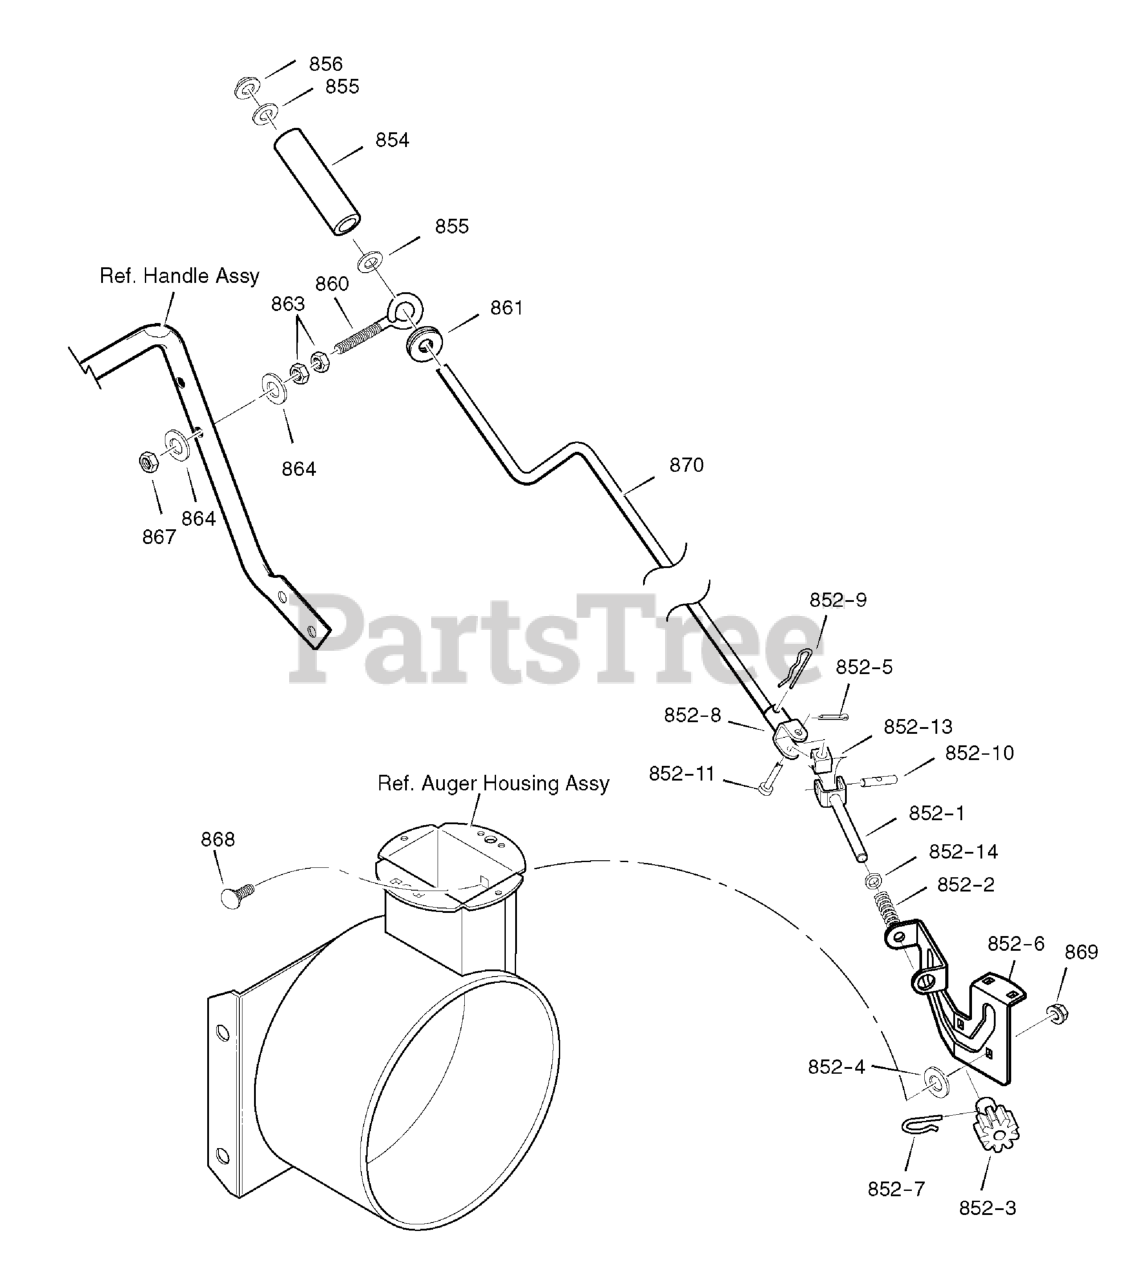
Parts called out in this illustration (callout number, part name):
852-1	YOKE & ROD ASSEMBLY
852-2	SPRING, Compression
852-3	GEAR, Chute Rotation
852-4	WASHER
852-5	PIN, Cotter
852-6	BRACKET, Gear Mount
852-7	PIN, Hair
852-8	YOKE ADAPTER ASSEMBLY
852-9	PIN, Hair
852-10	PIN, Universal Joint
852-11	PIN, Clevis
852-13	HOUSING, Universal
854	KNOB, Sleeve
855	FLATWASHER
856	NUT, Push On, 3/8
860	EYE BOLT 3/8 - 16 x 6
861	GROMMET, Eye Bolt
863	NUT, Hex Jam, 3/8 - 16
864	FLATWASHER
867	NUT, Hex Nylock, 3/8 - 16
868	BOLT, Carriage, 1/4 - 20 x 1
869	NUT
870	CHUTE ASSEMBLY
